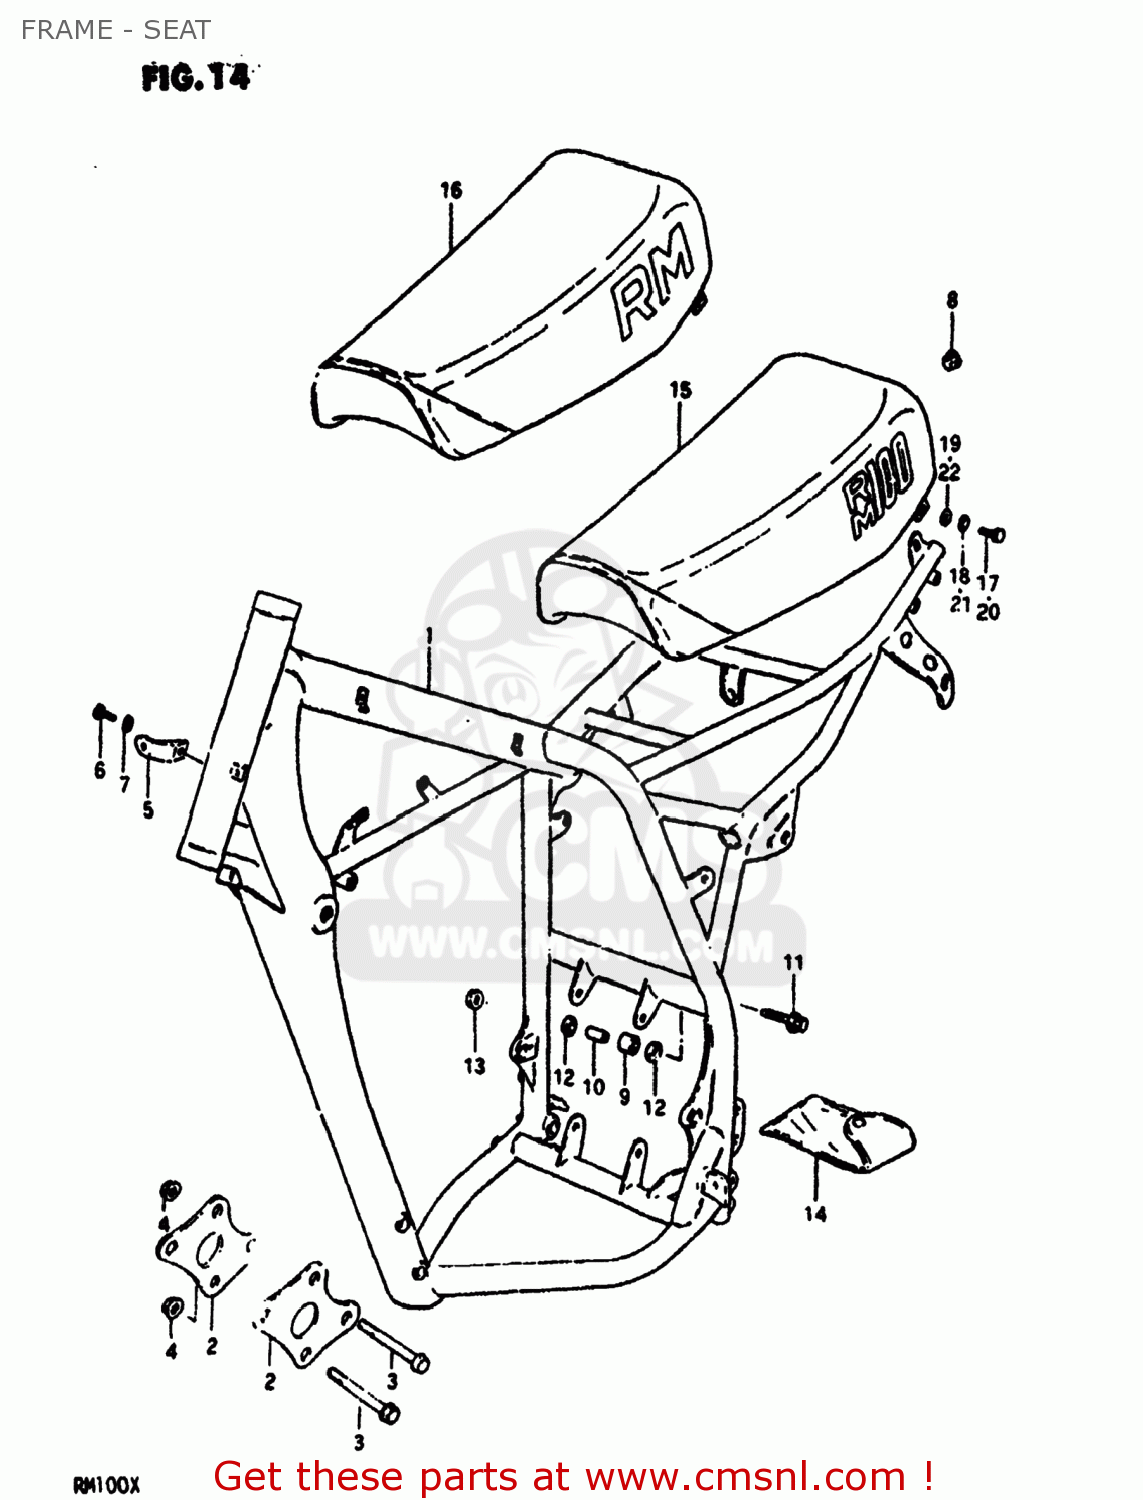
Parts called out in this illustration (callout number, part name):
1	FRAME
2	PLATE,ENGINE MOUNTING
3	BOLT(8X67)
4	NUT
5	PLATE,ENGINE MOUNTING
6	BOLT
7	LOCK WASHER
8	PLUG(OD:19)
9	ROLLER,CHAIN CONTROL
10	SPACER,CHAIN LENGTH ROLLER
11	BOLT(8X45)
12	WASHER
13	NUT
14	TOOL SET
15	SEAT ASSEMBLY
16	SEAT ASSEMBLY
17	BOLT, UPPER
18	LOCK WASHER
19	WASHER(6.5X18X1)
20	BOLT
21	LOCK WASHER
22	WASHER
